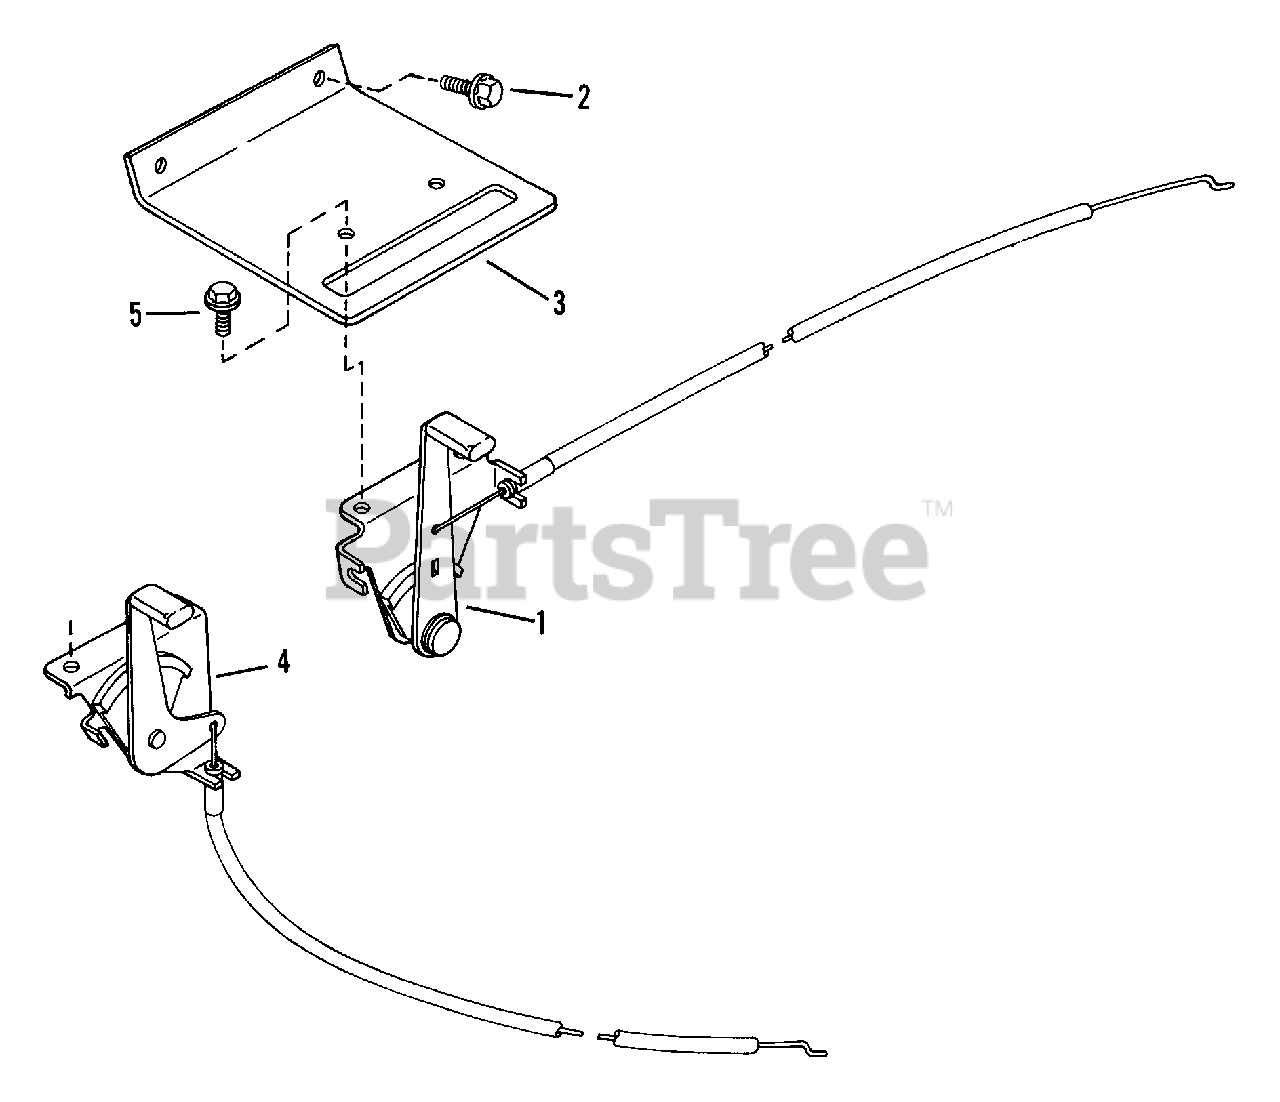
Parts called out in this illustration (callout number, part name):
1	CONTROL, Throttle
2	SCREW, 1/4-20 x 1/2" Self-Tapping
3	PLATE, Throttle Control
4	CONTROL, Throttle
5	SCREW, #10-24 x 1/2" Self-Tapping
